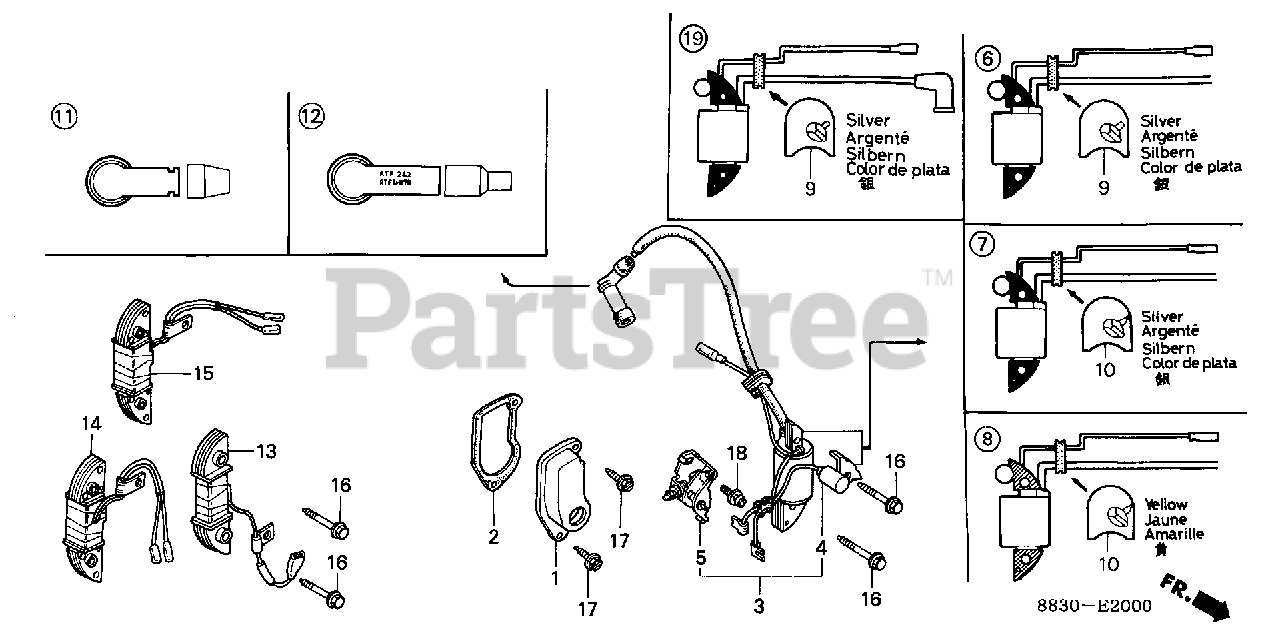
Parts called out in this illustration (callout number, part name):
1	COVER, BREAKER
2	GASKET, POINT COVER
4	CONDENSER
5	POINTS ASSY.
6	COIL ASSY., IGNITION
6	COIL ASSY., IGNITION Use up to Engine SN 1071267.
9	GROMMET, WIRE
11	TERMINAL ASSY., IGNITION (NOT AVAILABLE)
16	BOLT, FLANGE (6X32)
17	BOLT, FLANGE (5X10)
18	SCREW-WASHER (5X12)
